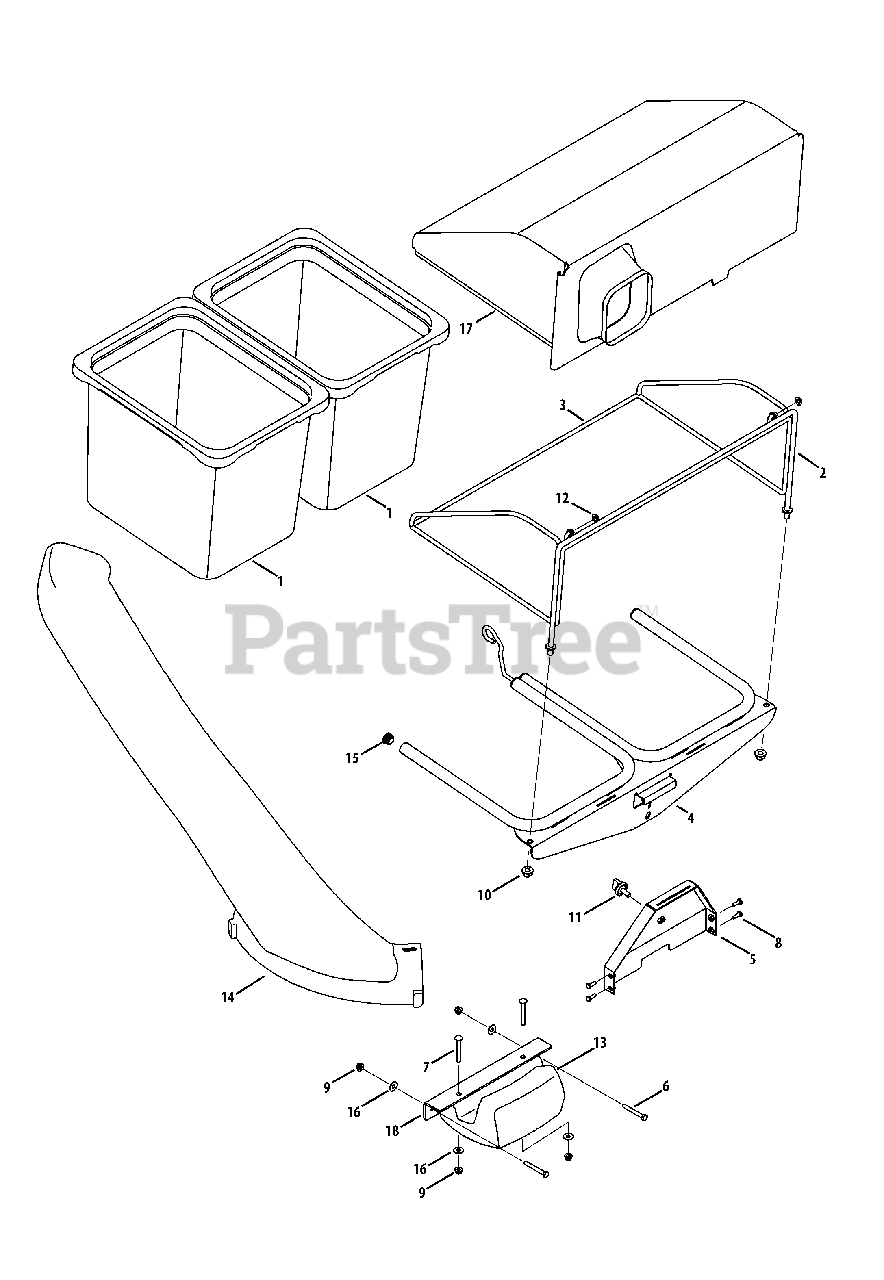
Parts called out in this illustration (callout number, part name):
2	Front Hood Assembly Frame
3	Rear Hood Assembly Frame
4	Bagger Support Assembly
5	Mounting Bracket
6	Hex Lock Screw, 5/16-18, 2.50
7	Carriage Bolt, 5/16-18, 2.50
8	Hex Head Screw, 1/4-20, .750
9	Flange Lock Nut, 5/16-18
10	Flange Lock Nut, 1/2-13
11	Knob, 3/8-16, .875
12	Push Cap, 3/8 Rod
14	Chute Tube
16	Flat Washer, .349 x .879 x .063
17	Grass Catcher Hood
18	Weight Mounting Bracket
